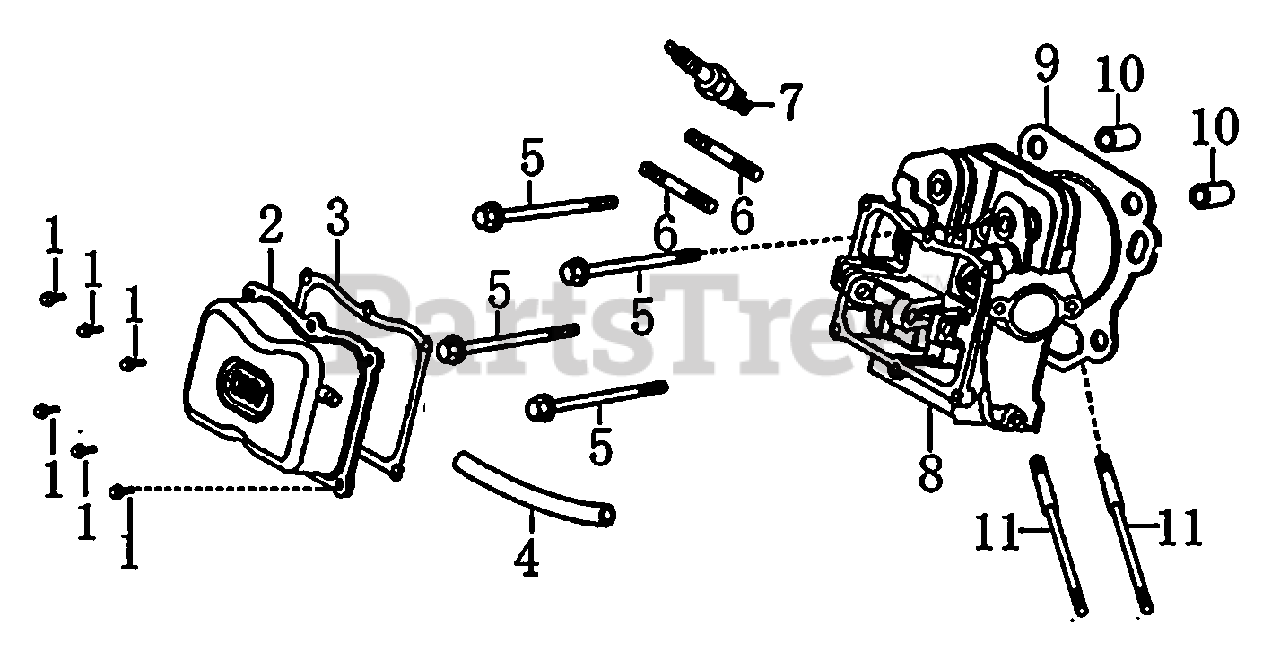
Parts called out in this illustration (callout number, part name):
1	BOLT, FLANGE
2	COVER, HEAD
3	GASKET, HEAD COVER
4	TUBE, BREATHER
5	BOLT, FLANGE HEAD 10X80
6	BOLT, STUD, EXHAUST
7	SPARK PLUG
8	HEAD, CYLINDER
9	GASKET, CYLINDER HEAD
10	PIN, DOWEL
11	BOLT, STUD, INTAKE
